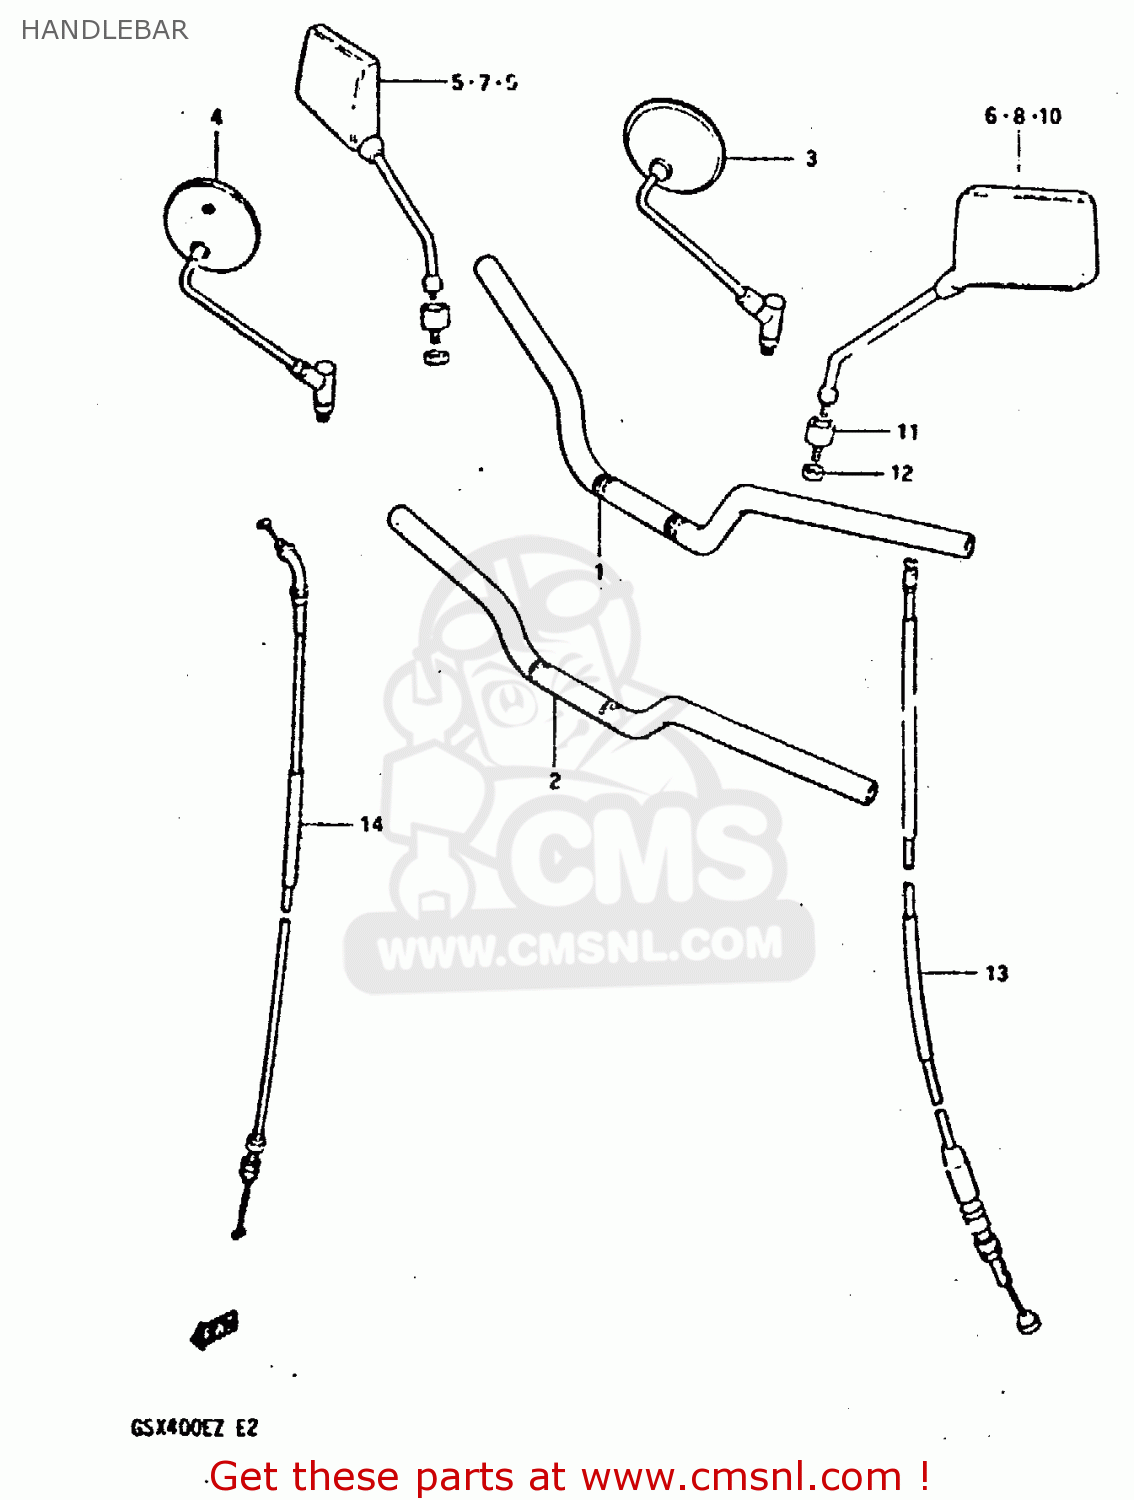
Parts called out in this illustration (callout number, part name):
1	HANDLEBAR
2	HANDLEBAR (FLAT HANDLEBAR)
3	MIRROR ASSY,RH
11	CUSHION,REAR VIEW MIRROR
12	NUT
13	CABLE ASSY,CLUTCH
14	CABLE ASSEMBLY,THROTTLE
